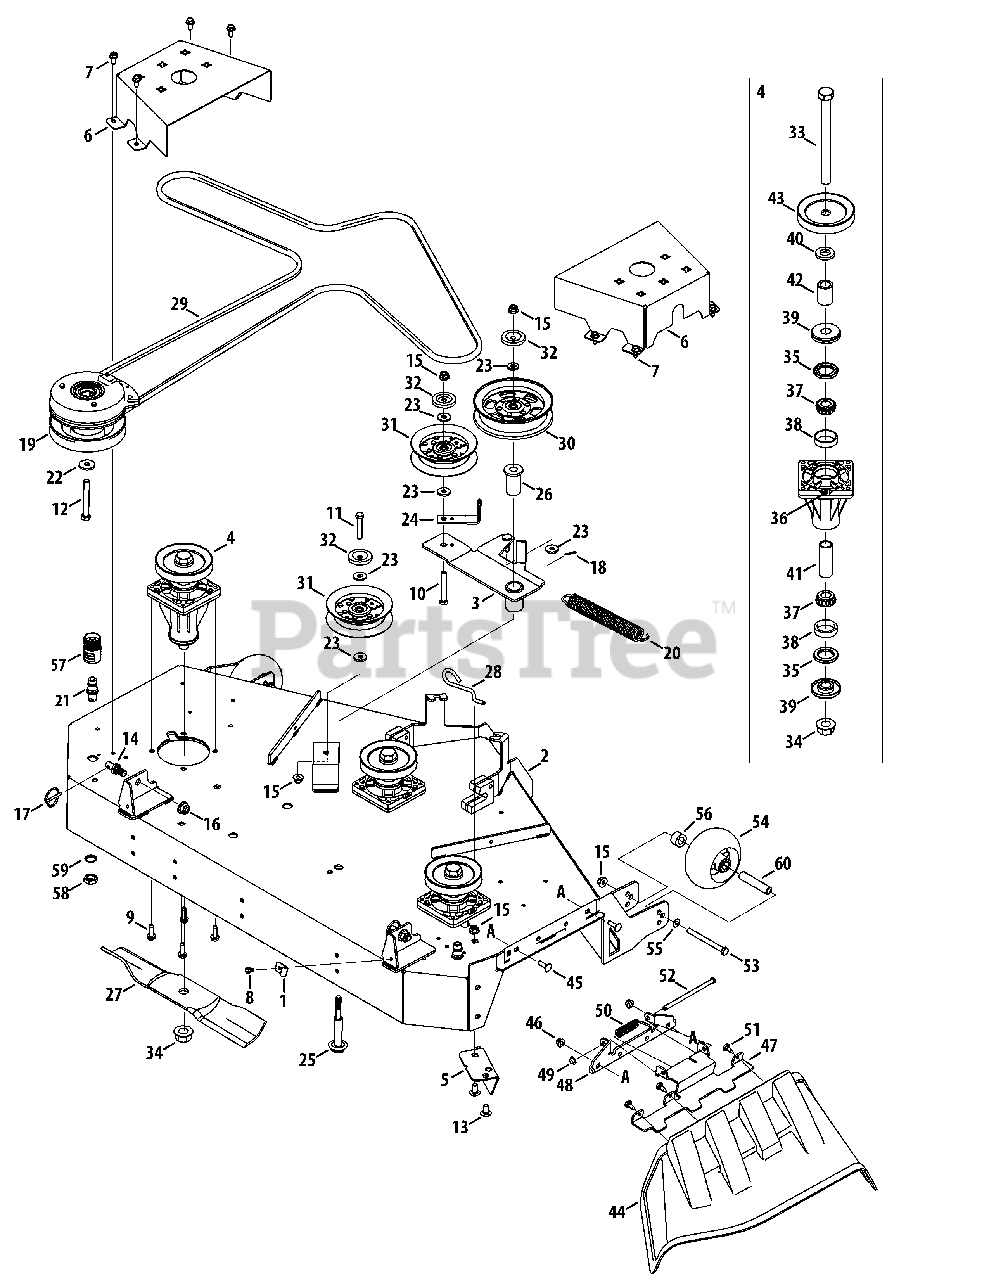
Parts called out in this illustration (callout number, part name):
1	Bracket, Hook Retainer
2	48" Deck
3	Deck Idler Assembly
4	Spindle Assembly
5	Chute Baffle
6	Belt Cover
7	Hex Washer Screw, 5/16-18 x .750
8	Hex Washer Screw, 1/4-20 x .500
9	Hex Washer Screw, 5/16-18 x 1.250
10	Hex Cap Screw, 3/8-16 x 2.50
11	Hex Cap Screw, 3/8-16 x 2.00
12	Screw, 7/16-20 x 3.25
13	Carriage Screw, 3/8-16 x .75
14	Pin, Shoulder Lock, .500
15	Flange Lock Nut, 3/8-16
16	Flange Lock Nut, 1/2-13
17	Pin, Lynch x .1875
18	Cotter Pin 3/32" Dia. x .75 Lg.
19	Electric PTO Clutch
20	Extension Spring, 1.25 OD x 1.751
21	Deck Water Nozzle
22	Flat Washer, .450 x 1.25 x .164
23	Flat Washer, .406 x .875 x .105
24	Belt Guard Bracket
25	Shoulder Boult, .625 x 2.12, 3/8-16
26	Shoulder Spacer, 1.055 x .627 x 2.292
27	Blade, 17.00
28	Deck Spring Rod
29	V-Belt
30	Idler Pulley, 5.00 Dia.
31	Idler Pulley, 4.00 Dia
32	Pulley Cap
33	Hex Cap Screw, 3/4-16 x 8.25
34	Nut, 3/4-16, Flangelock
35	Oil Seal
36	Grease Fitting
37	Cone Bearing
38	Cup Bearing
39	Spindle Spacer
40	Spacer, .812 ID x .218 LG
41	Spacer, .78 x 1.00 x 2.895
42	Spacer, .792 x 1.20 x 1.628
43	V-Type Pulley
44	Discharge Chute Assembly
45	Carriage Bolt, 5/16-18 x 1.00
46	Flange Lock Nut, 5/16-18
47	Chute Bracket
49	Push Cap
50	Torsion Spring
51	Shoulder Screw, 1/4-20
52	Chute Rod
53	Hex Cap Screw, 3/8-16 x 4.0
54	Deck Ball Wheel, 5.0
55	Flat Washer, .406 x .875 x .059
56	Shoulder Spacer, .500 x 3.09
57	Water Nozzle Adapter
58	Hex Nut, M-16 x 1.5
59	Lock Washer, 17 x 23.8 x 1.95
60	Spacer, .380 x .495 x 3.450
